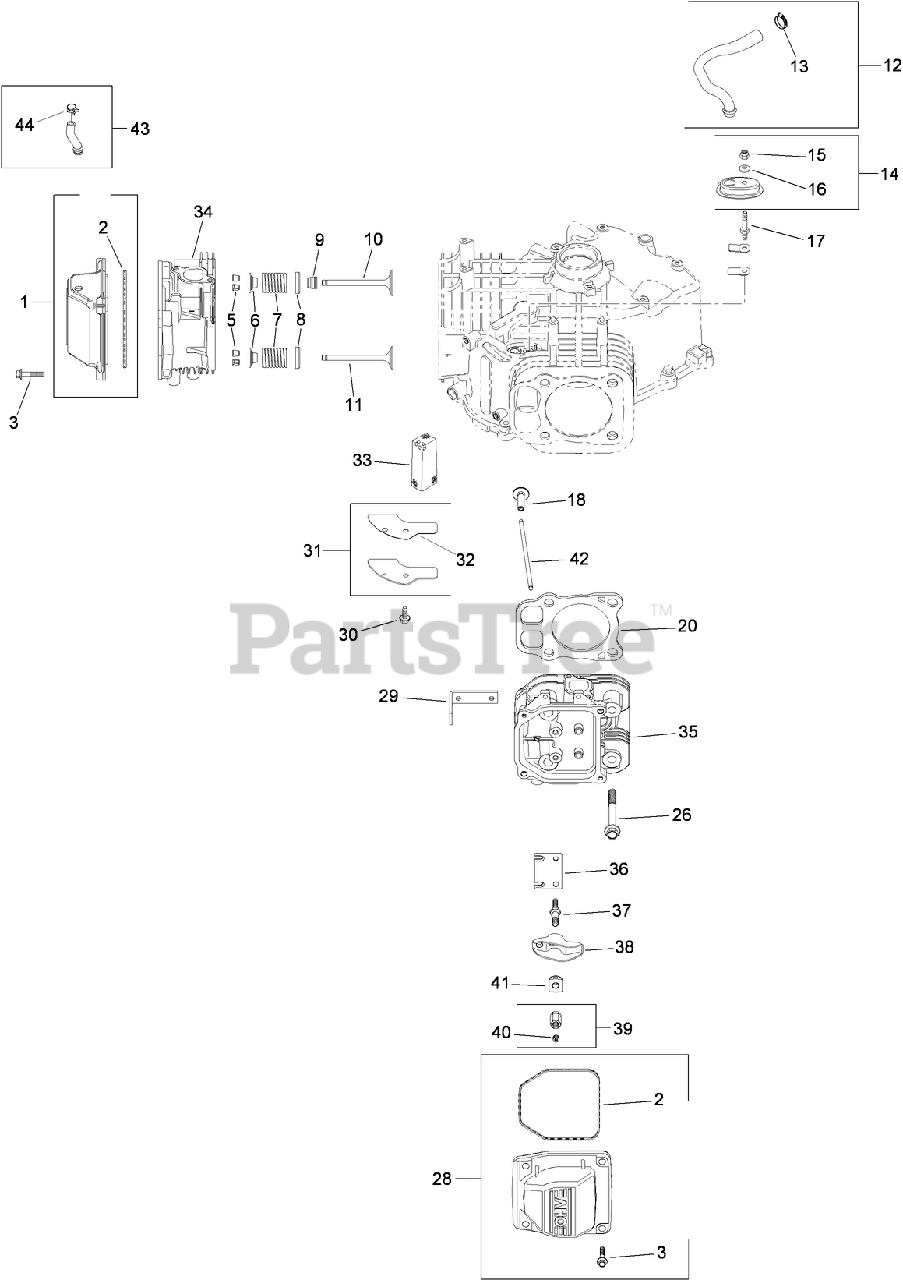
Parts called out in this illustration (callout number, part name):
1	BREATHER VALVE COVER KIT
2	O-RING
3	SCREW-FLANGE (M6X1.0X30)
5	RETAINER KIT
6	CAP-SPRING, VALVE
7	SPRING-VALVE
8	RETAINER-SPRING
9	SEAL-STEM, VALVE
10	VALVE-INTAKE (STD)
11	VALVE-EXHAUST (STD)
12	BREATHER HOSE KIT
13	CLAMP-HOSE, SPRING (1/2)
14	BREATHER HOUSING KIT (INCLUDES 15-16)
15	NUT-LOCK (M5X.8)
16	WASHER-SEALING
17	STUD-COVER, BREATHER
18	TAPPET KIT
20	CYLINDER HEAD GASKET KIT
26	SCREW-FLANGE (M10X1.5X90)
28	PLAIN ROCKER COVER KIT
29	STRAP-LIFTING
30	SCREW-FLANGE, THREAD FORMING (M6X1.0X16)
31	BREATHER COVER KIT
32	GASKET-COVER, BREATHER
33	FILTER-BREATHER
34	CYLINDER HEAD NO.1 ASM
35	CYLINDER HEAD NO.2 ASM
36	PLATE-GUIDE
37	STUD-ROCKER
38	ARM-ROCKER
39	HEX NUT ASM (INCLUDES REF 32)
40	SCREW-SET
41	PIVOT-ARM, ROCKER
42	ROD-PUSH
43	FUEL PUMP HOSE W/CLAMP KIT (INCLUDES REF 36)
44	CLAMP-HOSE
